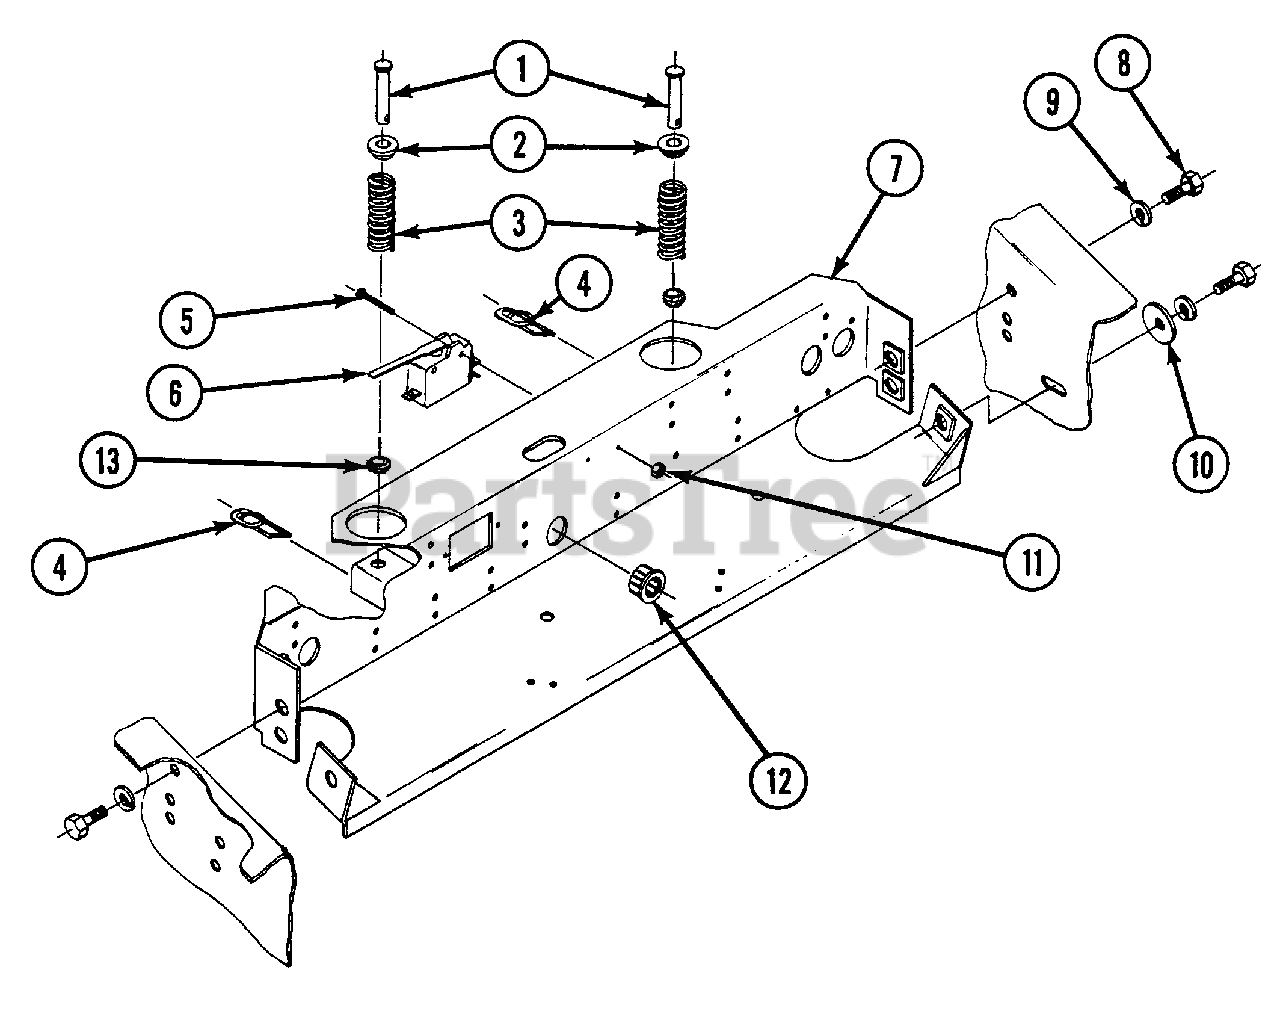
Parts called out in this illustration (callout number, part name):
1	PIN, CLEVIS, 5/16 X 1-3/4
2	WASHER SEAT SPRING
3	SPRINGER COMPRESSION, .720 X .081 X 2
4	COTTER, RUE RING, 5/16-3/8 PIN
5	SCREW, ROUNDHEAD, SLOTTED, 6-32 X 1
6	SWITCH, SINGLE POLE/DOUBLE THROW, 15A
7	SEAT STOP BRACKET WELDMENT
7	SEAT STOP BRACKET WELDMENT, JOYSTICK
8	CAPSCREW, HEX, 5/16-18 X 1, GRADE 5
9	LOCKWASHER, 5/16 HEAVY, SPLIT SPRING
10	WASHER 5/16 STD, FLAT
11	LOCKNUT, HEX, 6-32 W/NYLOC
12	BUSHINGS, PLASTICS WIRE PROTECTOR
13	WASHER, NYLON SEAT SPRING
